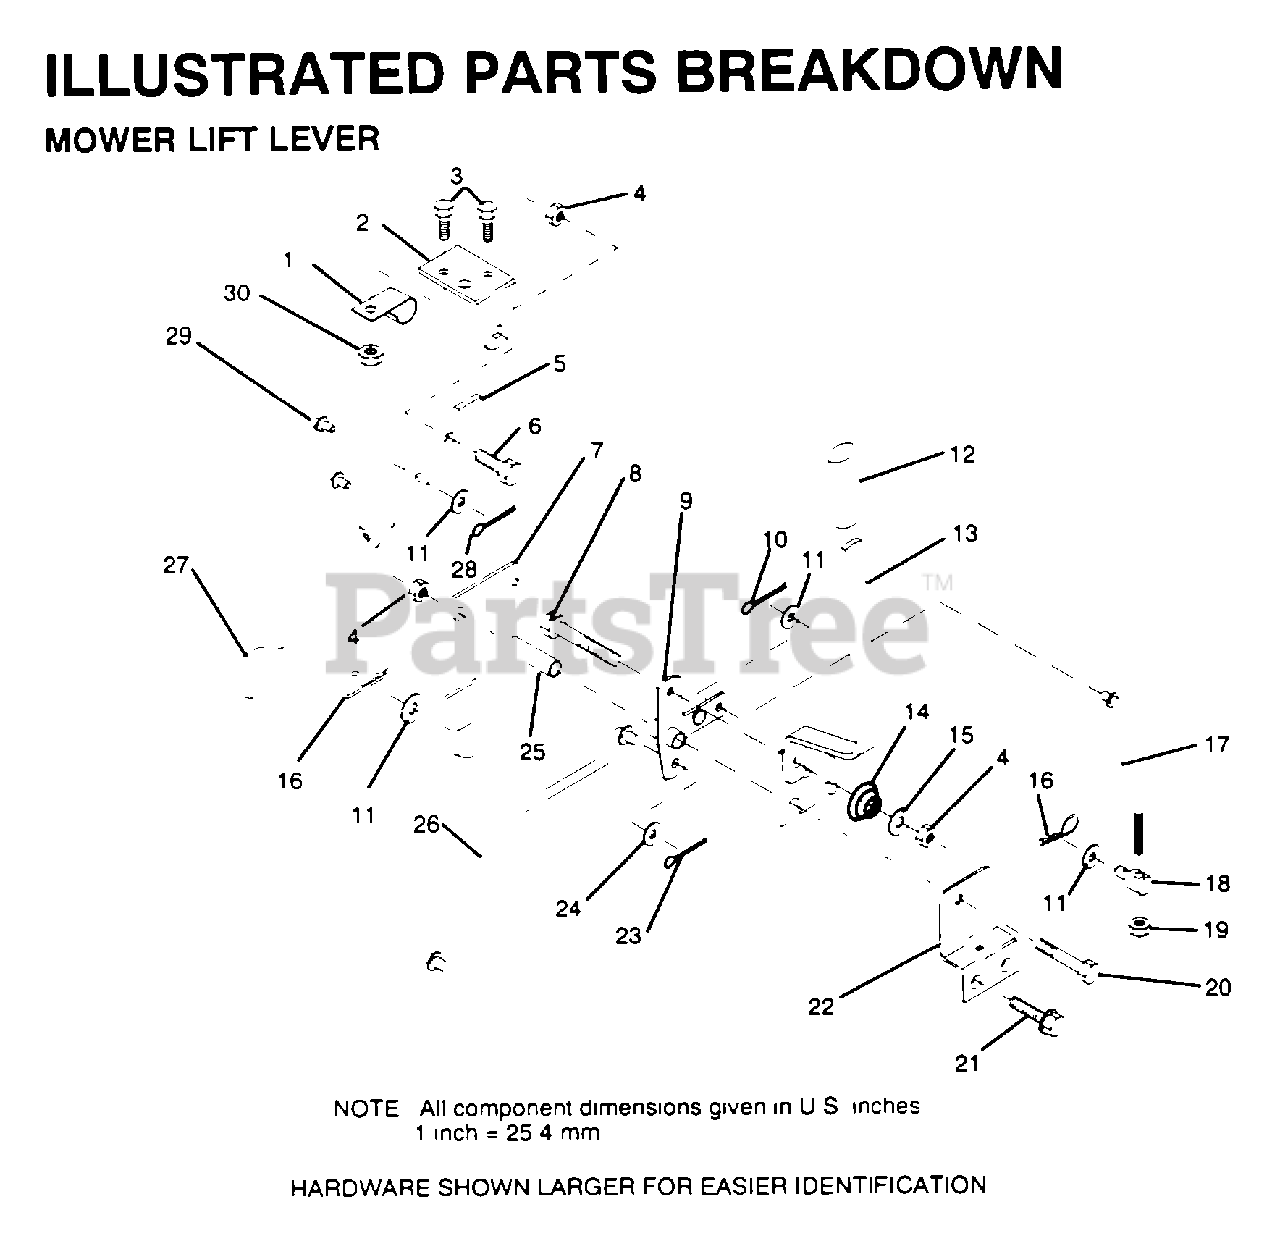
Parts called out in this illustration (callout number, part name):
1	"CLIP,INSULATOR"
2	BRKT CLUTCH
3	BOLT
5	CLUTCH LEVER AS
6	"BOLT, SHOULDER LT"
7	CLUTCH ARM ASS'Y
8	BOLT
9	"BELLCRANK,LIFT"
10	COTTER PIN
11	WASHER
12	GRIP HANDLE
13	"HDLE,LIFT T"
14	SPRING COMPRESSIO
15	WASHER T
16	SPRING.RETAINER
17	LINK FRT LIFT
19	NUT
20	BOLT
21	SCREW LT
22	"BRKT,MOWER HGT"
23	PIN COTTER 1/8
25	TUBE SPACER
26	"ROD,MOWER LIFT "
27	KNOB T(3/8 HOLE)
29	"LINK,MOWER LIFT"
